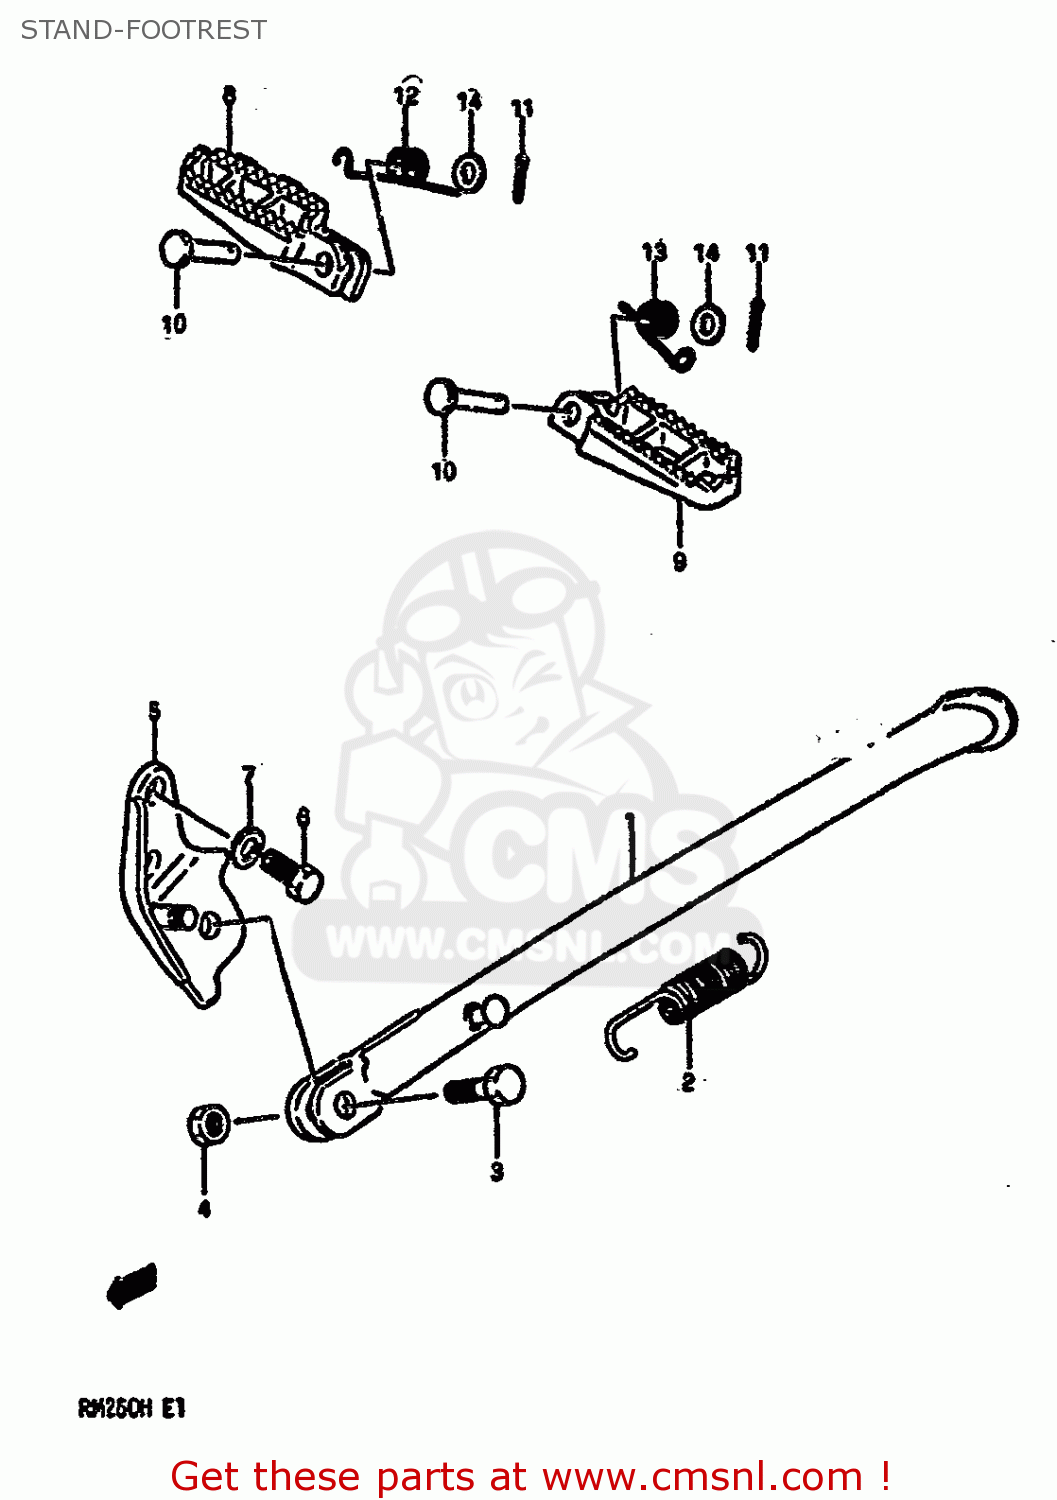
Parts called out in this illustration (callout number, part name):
1	STAND,SIDE
2	SPRING
3	BOLT(10X30)
4	NUT
5	BRACKET,SIDE STAND
6	BOLT(10X19)
7	WASHER,LOCK,10
8	FOOTREST
9	FOOTREST
10	PIN
11	PIN 20X20
12	SPRING
13	SPRING
14	WASHER
